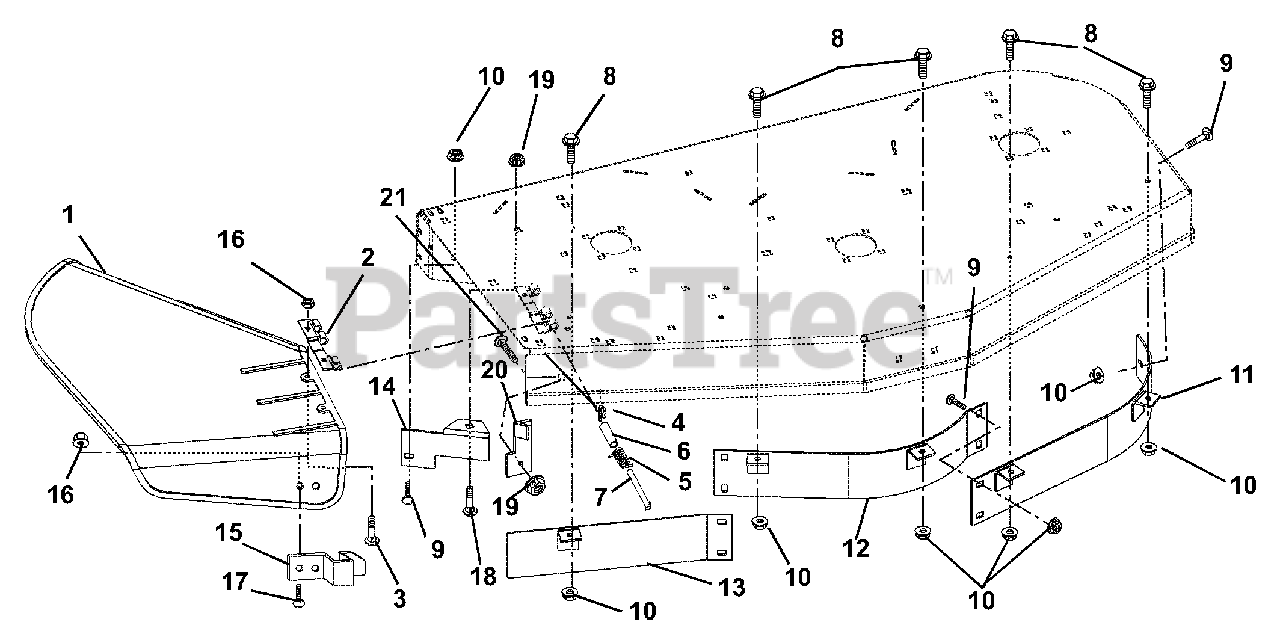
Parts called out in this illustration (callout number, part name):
1	Deflector, Chute
2	Hinge, Plate
3	Bolt, Round Head Square Neck .25-20 x .75 Grade 5
4	Pin, Internal .08 x .18 x 1.18
5	Spring, Torsion .095 x .50 x 1.00
6	Bushing, Sleeve
7	Pin, Clevis
8	Bolt, Serrated Hex Flange Washer Head .31-18 x .75
9	Bolt, Round Head Square Neck .31-18 x .75
10	Nut-.312-18 Flange Nyloc
11	Weldment, Upper Left Baffle-40"
11	Weldment, Upper Left Baffle-44"
11	Weldment, Upper Left Baffle-48"
11	Weldment, Upper Left Baffle-52"
12	Weldment, Upper Center Baffle-40"
12	Weldment, Upper Center Baffle-44"
12	Weldment, Upper Center Baffle-48"
12	Weldment, Upper Center Baffle-52"
13	Weldment, Upper Right Baffle-40"
13	Weldment, Upper Right Baffle-44"
13	Weldment, Upper Right Baffle-48"
13	Weldment, Upper Right Baffle-52"
14	Deflector, 40"
14	Deflector, 44"/48"
14	Deflector, 52"
15	Flat Spring
16	Nut, Locking Top Flange .25-20
17	Bolt, Round Head Square Neck .25-20 x .50 Grade 5
18	Bolt, Round Head Square Neck .38-16 x 1.00 Grade 5
19	Nut, Flange Nyloc .375-18
20	Bracket, Chute Lock
21	Bolt, Round Head Square Neck .38-16 x 1.50
